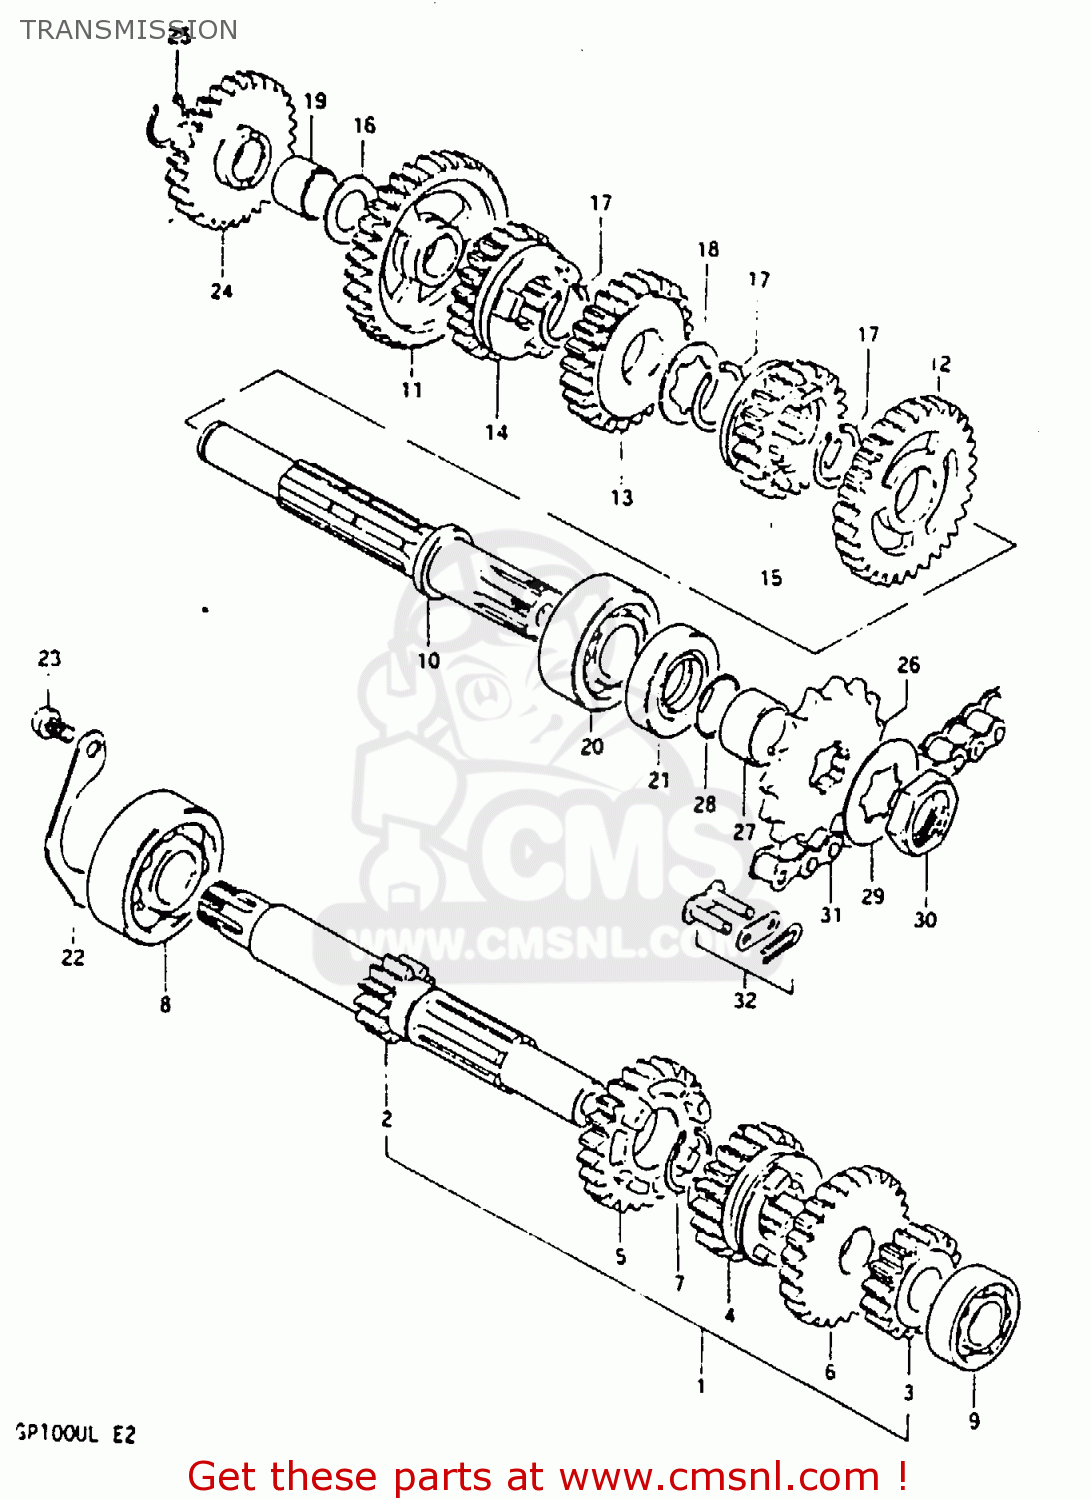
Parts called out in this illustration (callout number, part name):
1	COUNTERSHAFT ASSY
2	COUNTER SHAFT (NT:11)
3	GEAR,SECOND DRIVE
4	GEAR, 3RD DRIVE (NT:20)
5	GEAR, 4TH DRIVE (NT:23)
6	GEAR, 5TH DRIVE (NT:25)
7	CIRCLIP
8	BEARING
9	BEARING
10	DRIVESHAFT
11	GEAR,1ST DRIVEN
12	GEAR,2ND DRIVEN
13	GEAR, 3RD DRIVEN (NT:25)
14	GEAR, 4TH DRIVEN (NT:22)
15	GEAR, 5TH DRIVEN (NT:20)
16	WASHER,THRUST
17	CIRCLIP
18	WASHER,LOCK
19	BUSH
20	BEARING
21	SEAL,OIL(25X40X7)
22	RETAINER,CNTR SHAFT BEARING
23	SCREW 6X12
24	GEAR,KICK STARTER IDLER
25	CIRCLIP,15MM
26	SPROCKET,ENGINE
27	SPACER(20X25X12.5)
28	O RING(D:1,ID:19.5)
29	WASHER,LOCK
30	NUT
31	CHAIN ASSEMBLY,DRIVE
32	JOINT,CHAIN
